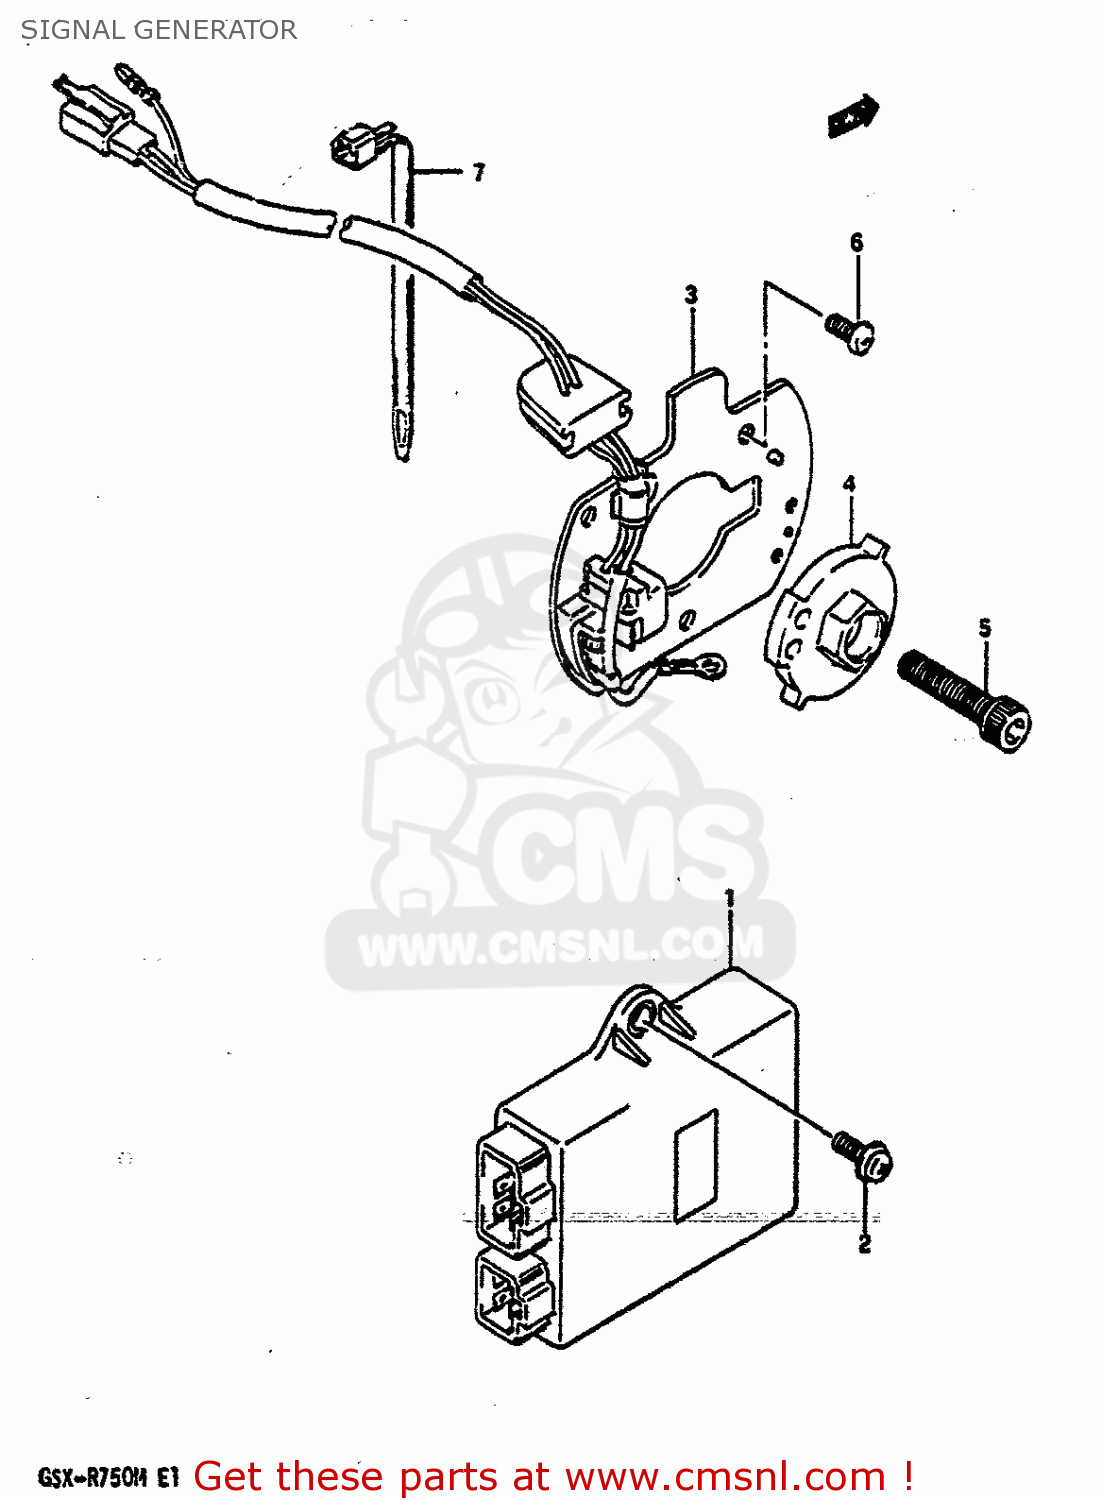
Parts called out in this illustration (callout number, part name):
1	IGNITOR
2	SCREW
3	GENERATOR ASSY,SIGNAL
4	ROTOR,SIGNAL
5	BOLT
6	SCREW
7	CLAMP(L:125)
